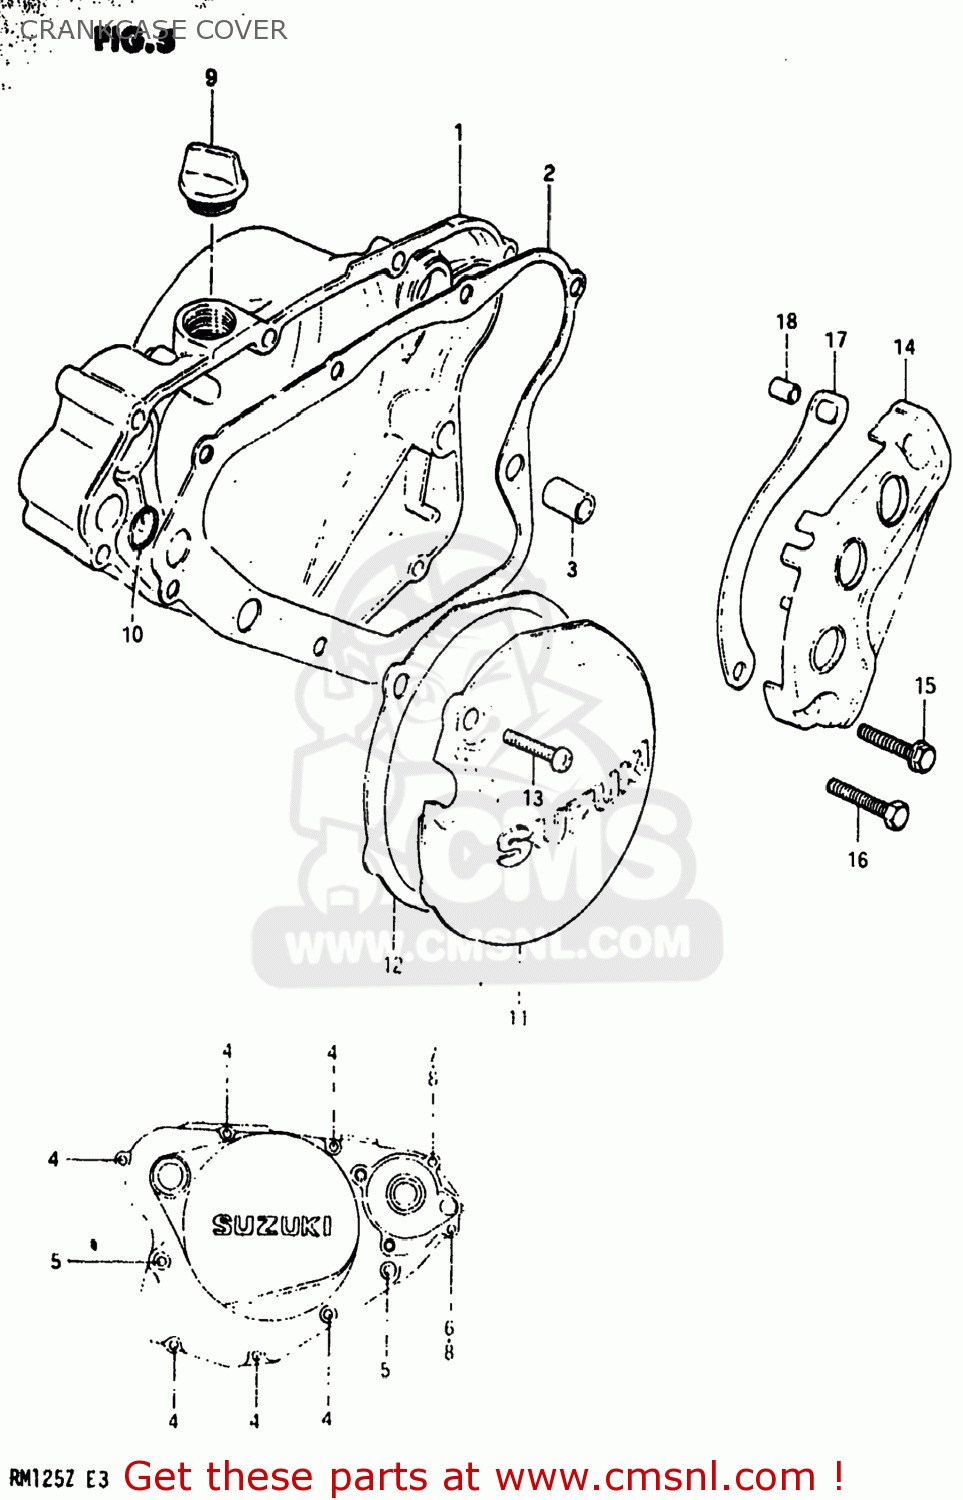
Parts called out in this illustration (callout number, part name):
1	COVER,CLUTCH
2	GASKET,CLUTCH COVER (MCA)
3	PIN
4	SCREW
5	SCREW (6X45)
6	CROSS SCREW (6 X 75)
7	SCREW 6X85
8	SCREW 6X70
9	PLUG,OIL FILTER
10	O RING(D:1.9,ID:14.5)
11	COVER,MAGNETO
12	GASKET,MAGNETO COVER (MCA)
13	SCREW
14	COVER,ENGINE SPROCKET
15	BOLT
16	BOLT 6X40
17	PLATE,CHAIN FRONT GUIDE
18	SPACER(6.5X10.5X12)
